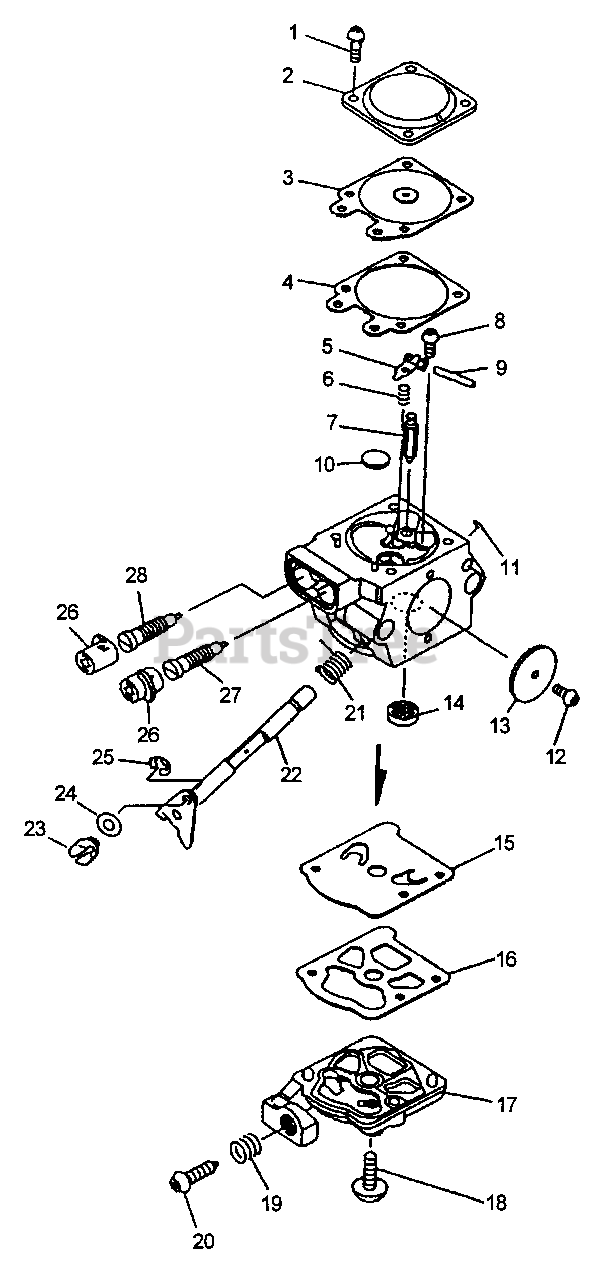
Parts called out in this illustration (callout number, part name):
2	COVER, METERING
3	DIAPHRAGM, METERING
4	GASKET, METERING
5	LEVER, METERING
6	SPRING, METERING LEVER
7	VALVE, INLET NEEDLE
8	SCREW, METERING LEVER PIN
9	PIN, METERING LEVER
10	PLUG, WELCH
11	RING, RETAINING
12	SCREW
13	VALVE, THROTTLE
14	STRAINER
15	DIAPHRAGM, PURGE
16	GASKET, PURGE
17	COVER, PUMP
18	SCREW, PUMP COVER
19	SPRING, IDLE ADJUST
20	SCREW, IDLE ADJUST
21	SPRING, THROTTLE RETURN
22	SHAFT, THROTTLE
24	WASHER
25	RING, RETAINING
26	CAP, LIMITER
27	NEEDLE - LOW SPEED
28	NEEDLE - HIGH SPEED
